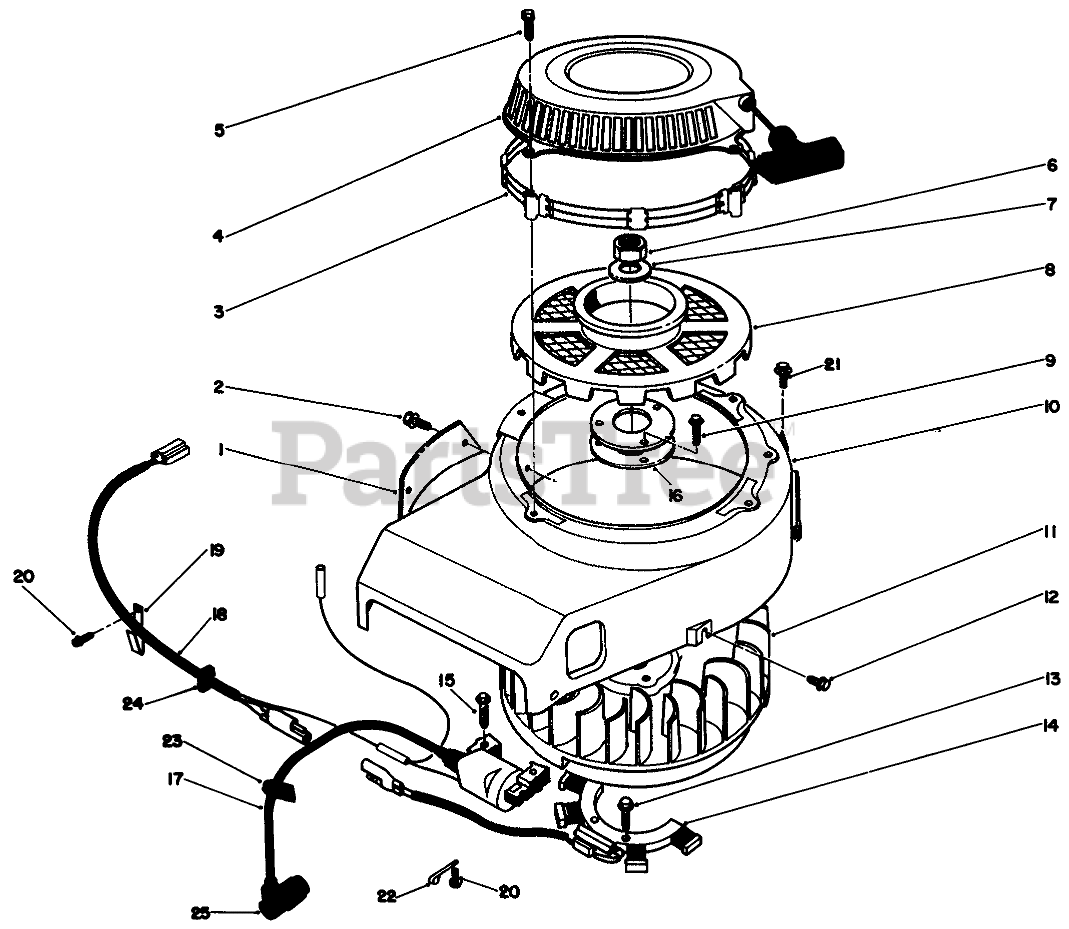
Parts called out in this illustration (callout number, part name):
1	Cover
4	Recoil Starter ASM
5	Bolt-Flanged (6X35)
9	Bolt-Flanged (8X12)
10	Housing-Fan
11	Flywheel
12	BOLT-FLANGED (6X10)
15	Bolt
17	Coil
19	Clamp
20	Bolt-Flanged (6X10)
21	Bolt-Flanged (6X14)
25	Cap-Spark
